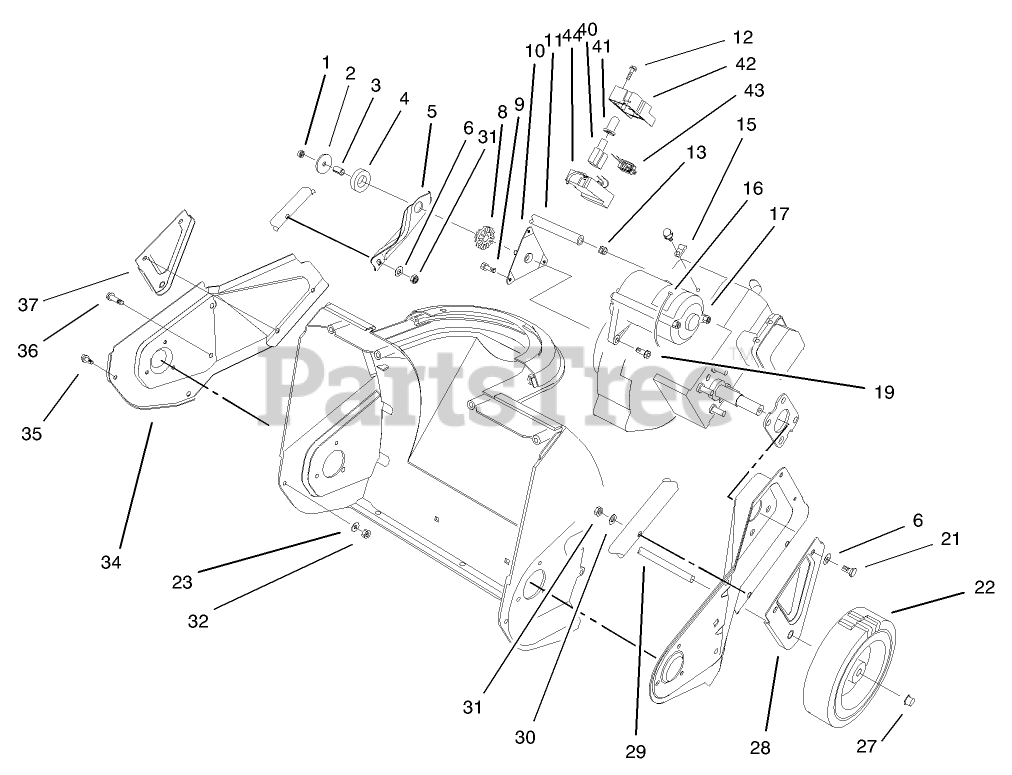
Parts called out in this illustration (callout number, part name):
1	NUT-LOCK, NI
3	SPACER-TUBULAR
4	RING-ISOLATOR
5	BRACKET-SUPPORT, ENGINE
6	WASHER-FLAT
8	BUSHING-ISOLATOR
9	SCREW
10	BRACKET AND STUD ASM
11	LINE-GAS
12	SCREW-PLASTITE
13	CLAMP-HOSE
15	CLAMP
16	TIE-CABLE
19	SCREW-HH, TORX
21	SCREW-HH
22	WHEEL
23	WASHER-FLAT
27	NUT-PUSH
28	BRACKET-WHEEL, LH
29	AXLE SHAFT
30	WASHER
31	NUT-LOCK, NI
32	NUT-LOCK, NI
34	PLATE-SIDE, RH
36	SCREW-PLASTIC
37	BRACKET-WHEEL, RH
40	SWITCH-STARTER
41	BOOT-SWITCH
42	HOUSING-CAP, SWITCH
43	PLUG-POWER
44	SWITCH-BASE, HOUSING
